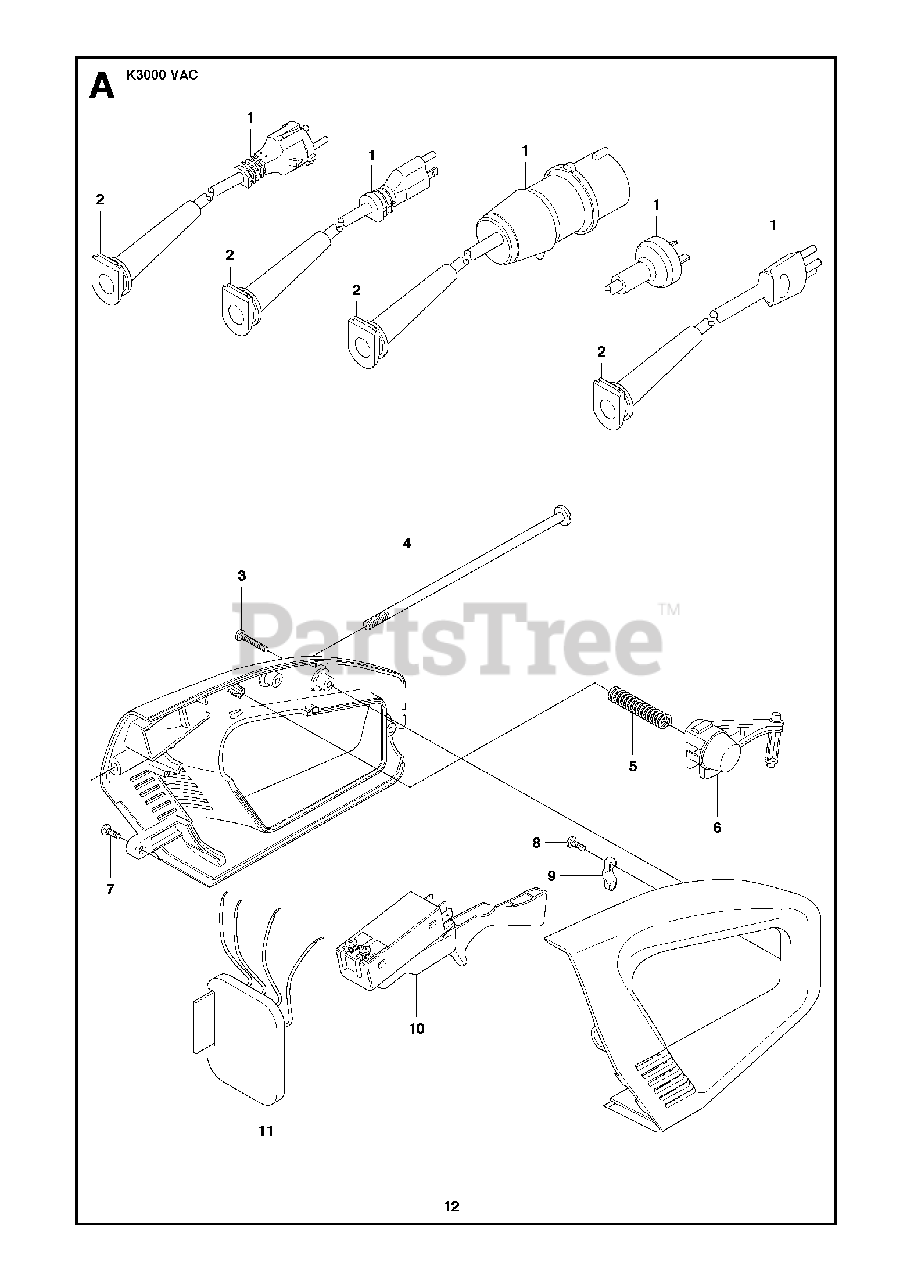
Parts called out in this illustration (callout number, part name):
1	CABLE110V JP, USA, incl. 2
1	CABLE110V UK, incl. 2
1	CABLE230V CH, incl. 2
2	CABLE SLEEVE
5	SPRING
6	LOCKING BUTTON
7	SCREW CRPANM
11	PRINTED CIRCUIT ASSY110V
11	PRINTED CIRCUIT ASSY230V
12	HANDLE ASSY
